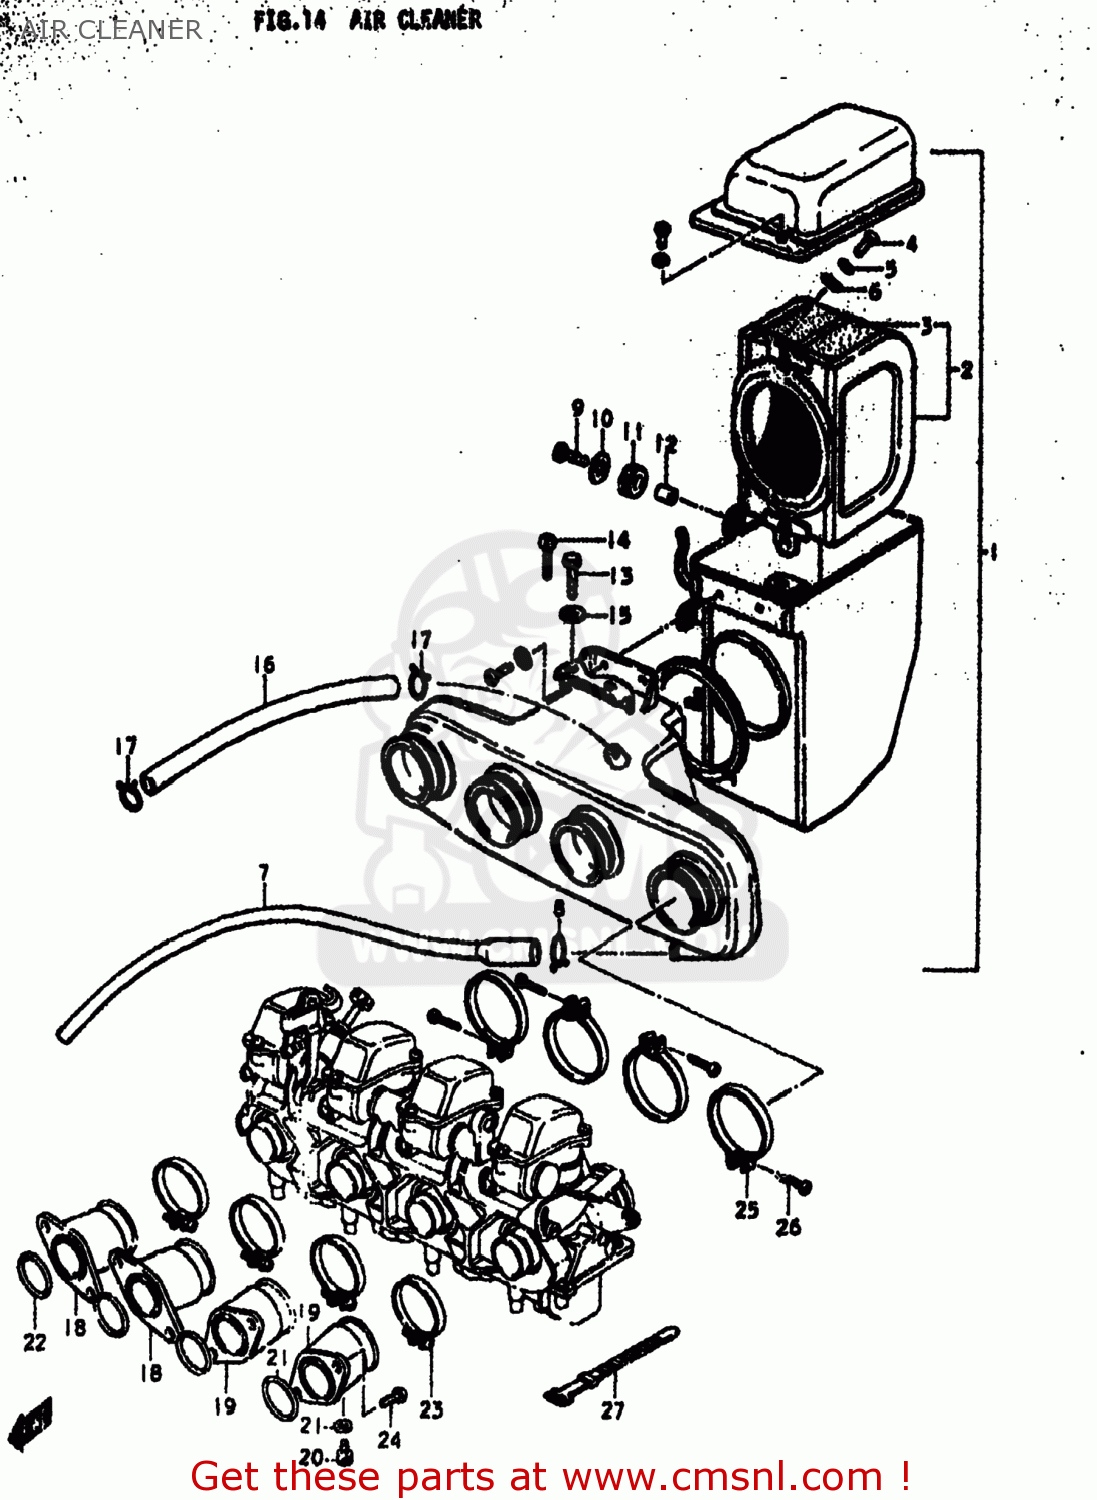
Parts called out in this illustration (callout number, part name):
1	CLEANER ASSEMBLY,AIR
2	FILTER ASSY
3	ELEMENT,AIR CLEANER
4	SCREW
5	LOCK WASHER
6	WASHER
7	HOLDER,FILTER
8	HOSE,AIR CLEANER
9	BOLT
10	WASHER
11	CUSHION
12	SPACER (6.1X9X9)
13	BOLT
14	SCREW 6X12
15	WASHER
16	HOSE
17	CLIP
18	PIPE,INTAKE
19	PIPE,INTAKE
20	BOLT
21	WASHER
22	O RING(D:2.4,ID:28.7)
23	CLAMP
24	SCREW
25	CLAMP
26	SCREW
27	CLAMP(L:120)
